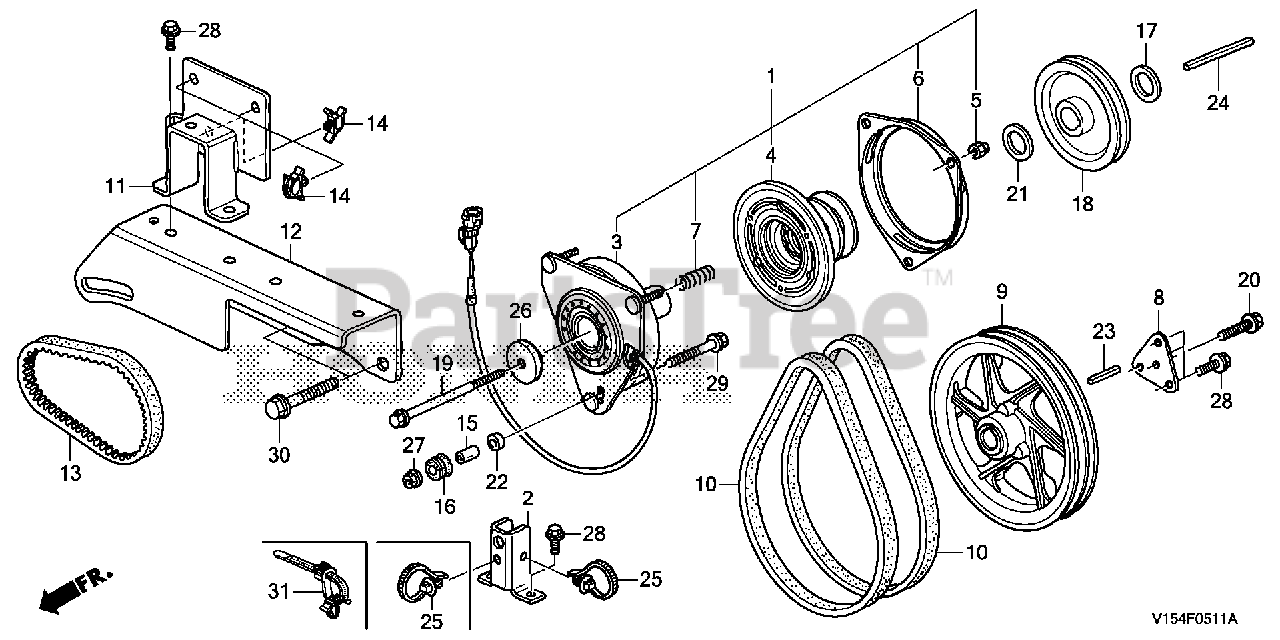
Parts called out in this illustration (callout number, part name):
1	CLUTCH-BRAKE ASSY.
5	NUT, HEX. (3/8-24UNF)
6	COVER, BRAKE
7	SPRING, RETURN
8	PATCH, PULLEY
9	PULLEY, AUGER DRIVEN
10	V-BELT (LB-36)
11	BRACKET, ALTERNATOR
12	STAY, ALTERNATOR
13	BELT, ALTERNATOR
14	CLIP, WIRE HARNESS
15	COLLAR, STEP (LOWER)
16	BUSH, RUBBER (NOT AVAILABLE)
17	COLLAR, DISTANCE (25MM)
18	PULLEY, ENGINE
19	BOLT, UBS (8X95) (NOT AVAILABLE)
20	BOLT, FLANGE (8X20)
21	WASHER (35MM)
22	COLLAR, MUFFLER MOUNTING
23	KEY (7X7X42)
24	KEY (7X7X103)
26	COLLAR, CLUTCH
27	NUT, FLANGE (8MM)
28	BOLT, FLANGE (8X16) Use from Engine SN 1000016.
29	BOLT, FLANGE (8X38)
30	BOLT, FLANGE (10X16)
31	BAND, WIRE HARNESS
